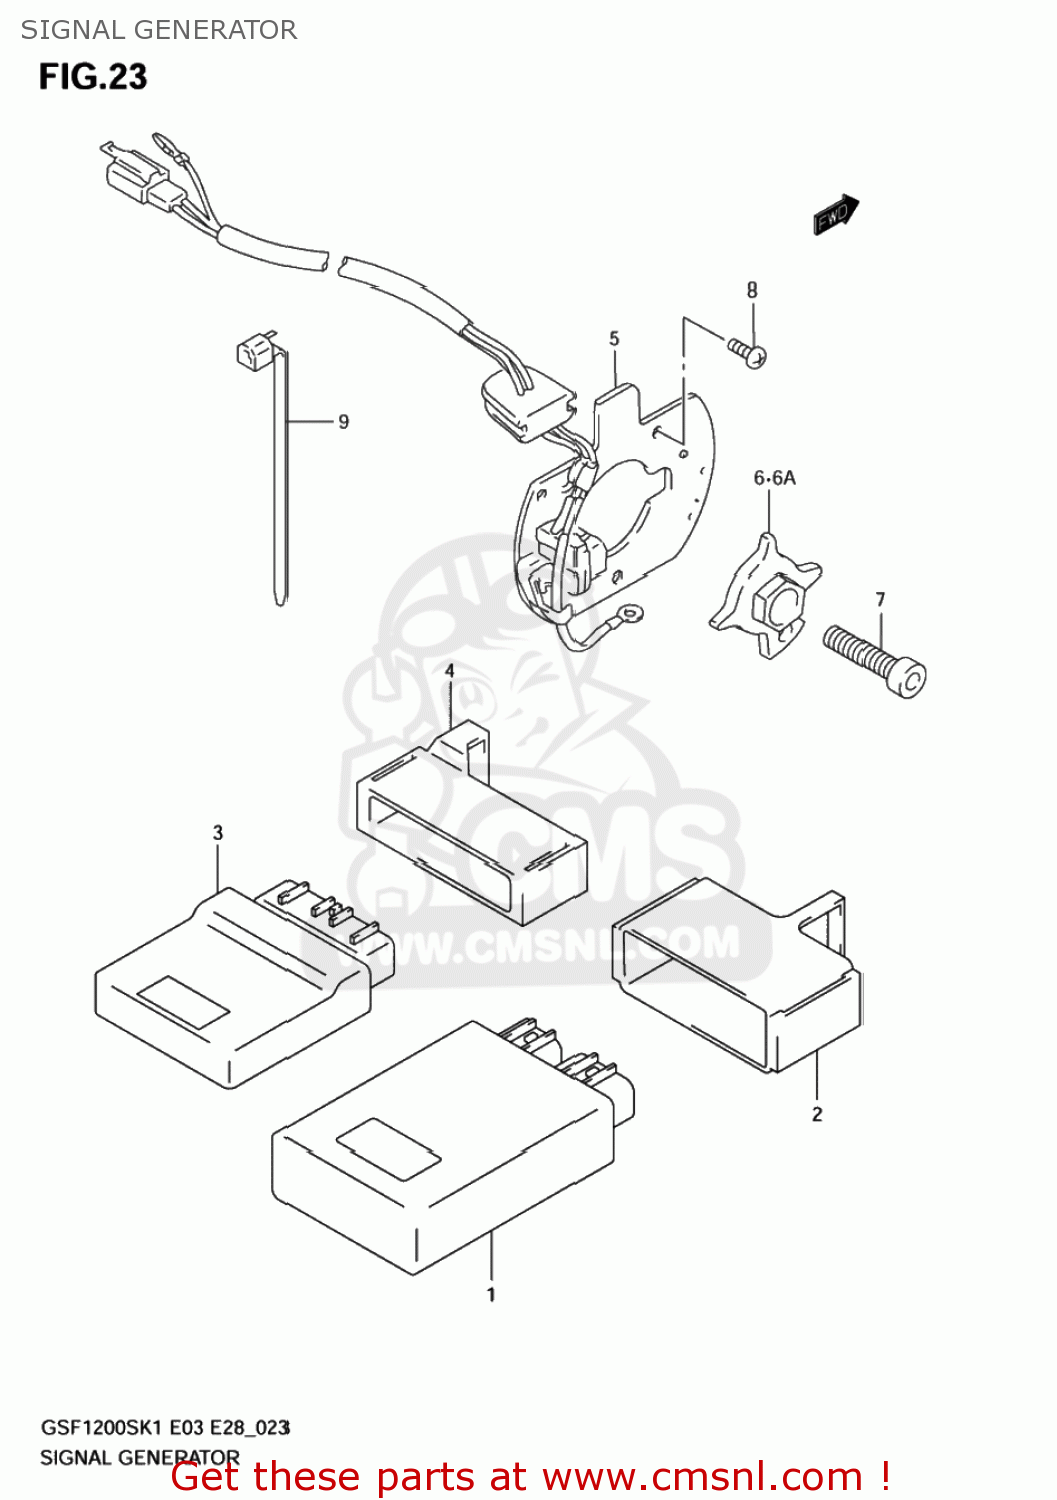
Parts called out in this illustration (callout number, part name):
1	IGNITOR ASSY
2	CUSHION,IGNITOR
3	IGNITOR ASSY
4	COVER,IGNITOR
5	STATOR,SIGNAL GENERATOR
6	ROTOR,SIGNAL GENERATOR
6A	ROTOR,SIGNAL
7	BOLT
8	SCREW
9	CLAMP(L:125)
